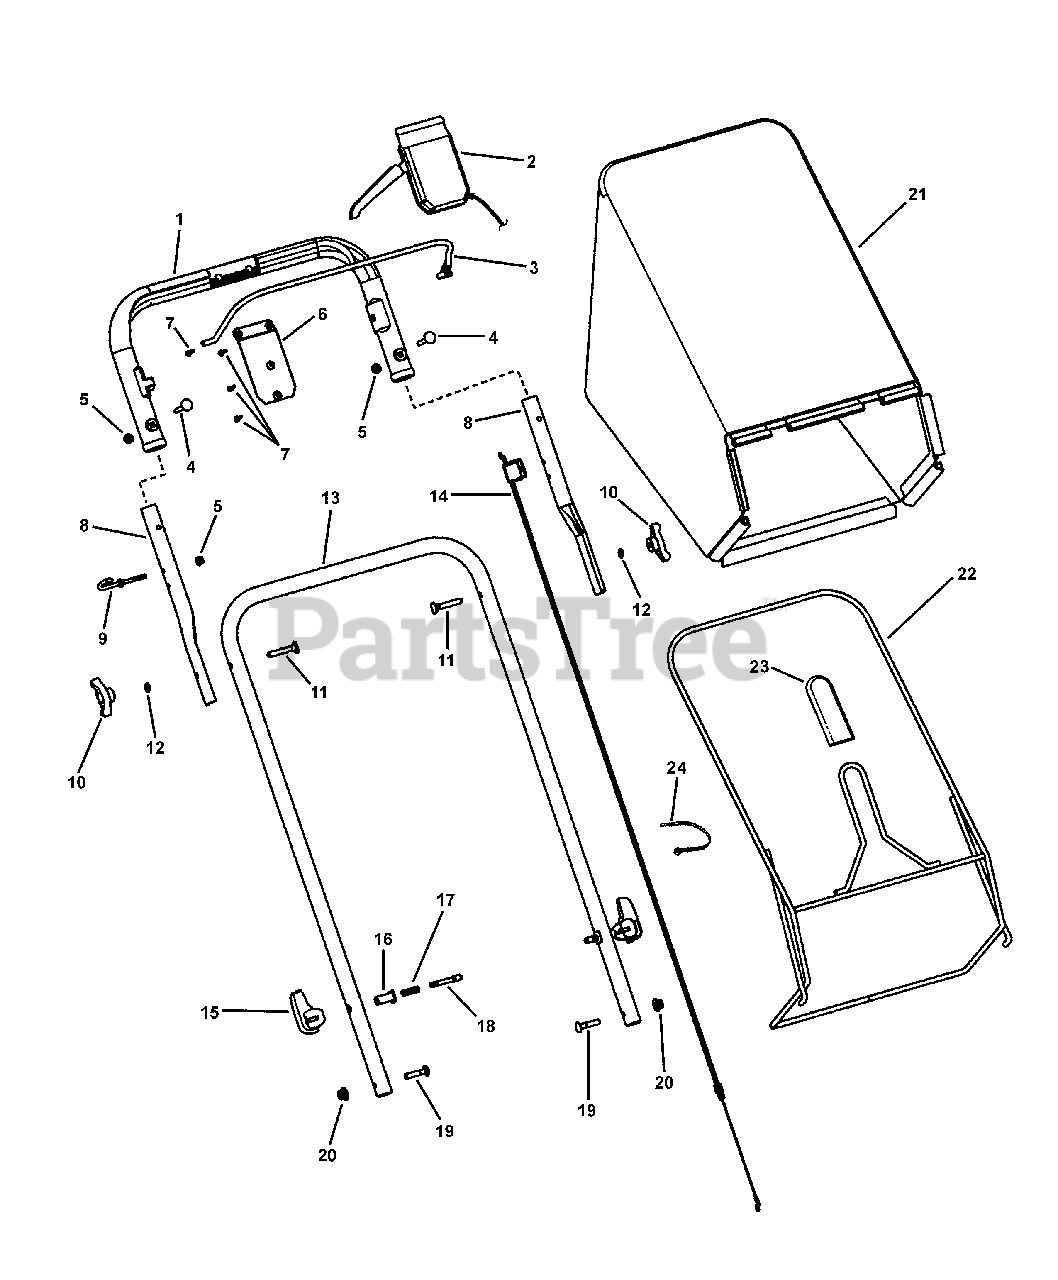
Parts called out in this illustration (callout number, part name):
1	UPPER HANDLE, Plastic, WBM
2	ASSY, Control Head, 22" WBM, Single Speed
3	BAIL, Plastic Handle, WBM
4	BOLT, 1/4-20 x 1-3/4" Round Head Square Neck, GR 2, YZ
5	NUT, 1/4-20, Hex Flange (Nyloc) YZ
6	PLATE, Control Panel
7	SCREW, #8-16 x 5/8" Recessed Pan Head Twin Helix (Torx)
8	HANDLE, Connecting, 21"/22" WBM
9	GUIDE, Rope (1/4-20 thread)
10	KNOB, 5/16-18 Wing (5/16-18 thread) (Black)
11	BOLT, 5/16-18 x 2" Curved Head Square Neck, GR 2
12	WASHER, 5/16" Internal Tooth Lock
13	HANDLE, Lower, 22" WBM
14	CABLE, Bail, 22" WBM
15	KNOB, Quick Release
16	BUSHING, Handle Pin
17	SPRING, Compression
18	PIN, Handle Adjust
19	BOLT, 5/16-18 x 1-1/2" Round Head Short Square Neck, GR 5
20	NUT, 5/16-18 Large Flange Center Lock
21	GRASS BAG, 22" Rear Discharge
22	BAG FRAME, 22" WBM (Weldment)
23	GRIP, Rectangular (Black)
24	WIRE TIE, 11" Standard Black Nylon
